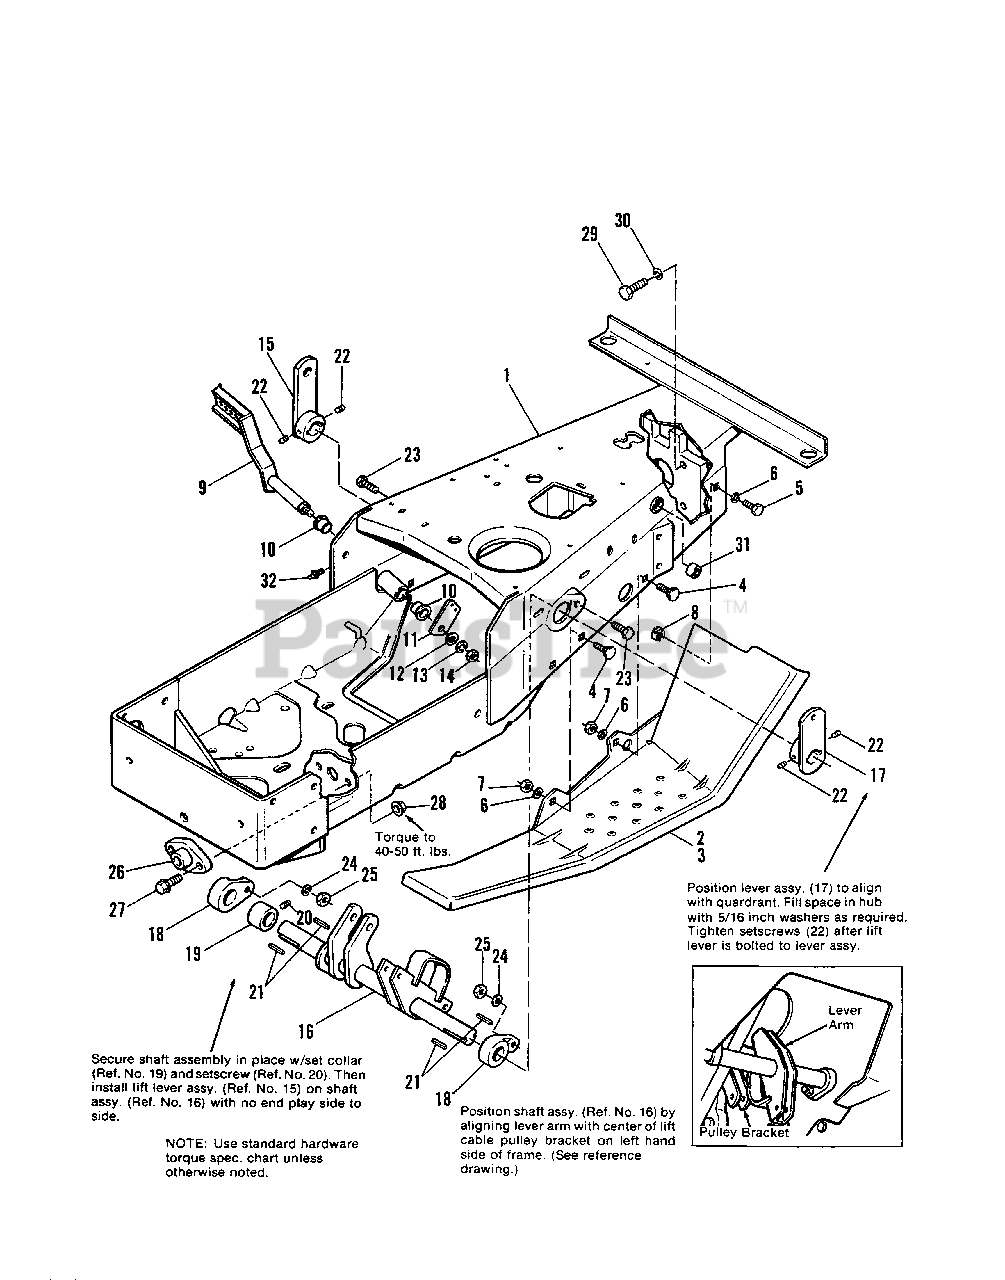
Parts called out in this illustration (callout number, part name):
1	FRAME & BUSHING ASSY.
2	FOOTREST, R.H.
3	FOOTREST, L.H.
4	BOLT, Carriage, 5/16-18 x 3/4
5	CAPSCREW, Hex Hd., 5/16-18 x 3/4
6	LOCKWASHER, 5/16
7	NUT, Hex, Full, 5/16-18
8	NUT, Speed, Tinnerman, 5/16-18
9	FOOT PEDAL ASSY.
11	ARM, Foot Pedal
12	WASHER, 3/8
13	LOCKWASHER, 3/8
14	NUT, Hex, Full, 3/8-16
15	FRONT LIFT LEVER ASSY. (R.H.)
16	LIFT SHAFT ASSY.
17	LIFT LEVER ASSY. (L.H.)
18	BEARING, Lift Lever
19	COLLAR, Set
20	SETSCREW, Cup Pt., 5/16-18 x 3/8
22	SETSCREW, Skt. Hd., 5/16-18 x 1/4
23	CAPSCREW, Hex Hd., 5/16-18 x 1-1/4
24	LOCKWASHER, 5/16
25	NUT, Hex, Full, 5/16-18
26	BEARING, Pivot
27	CAPSCREW, Hex, Whiziock, 3/8-16 x 1-1/4
28	LOCKNUT, Hex, Flange, Whiz, 3/8-16
29	CAPSCREW, Hex Hd., 7/16-14 x 1-1/2
30	LOCKWASHER, 7/16
32	FITTING, Lube
